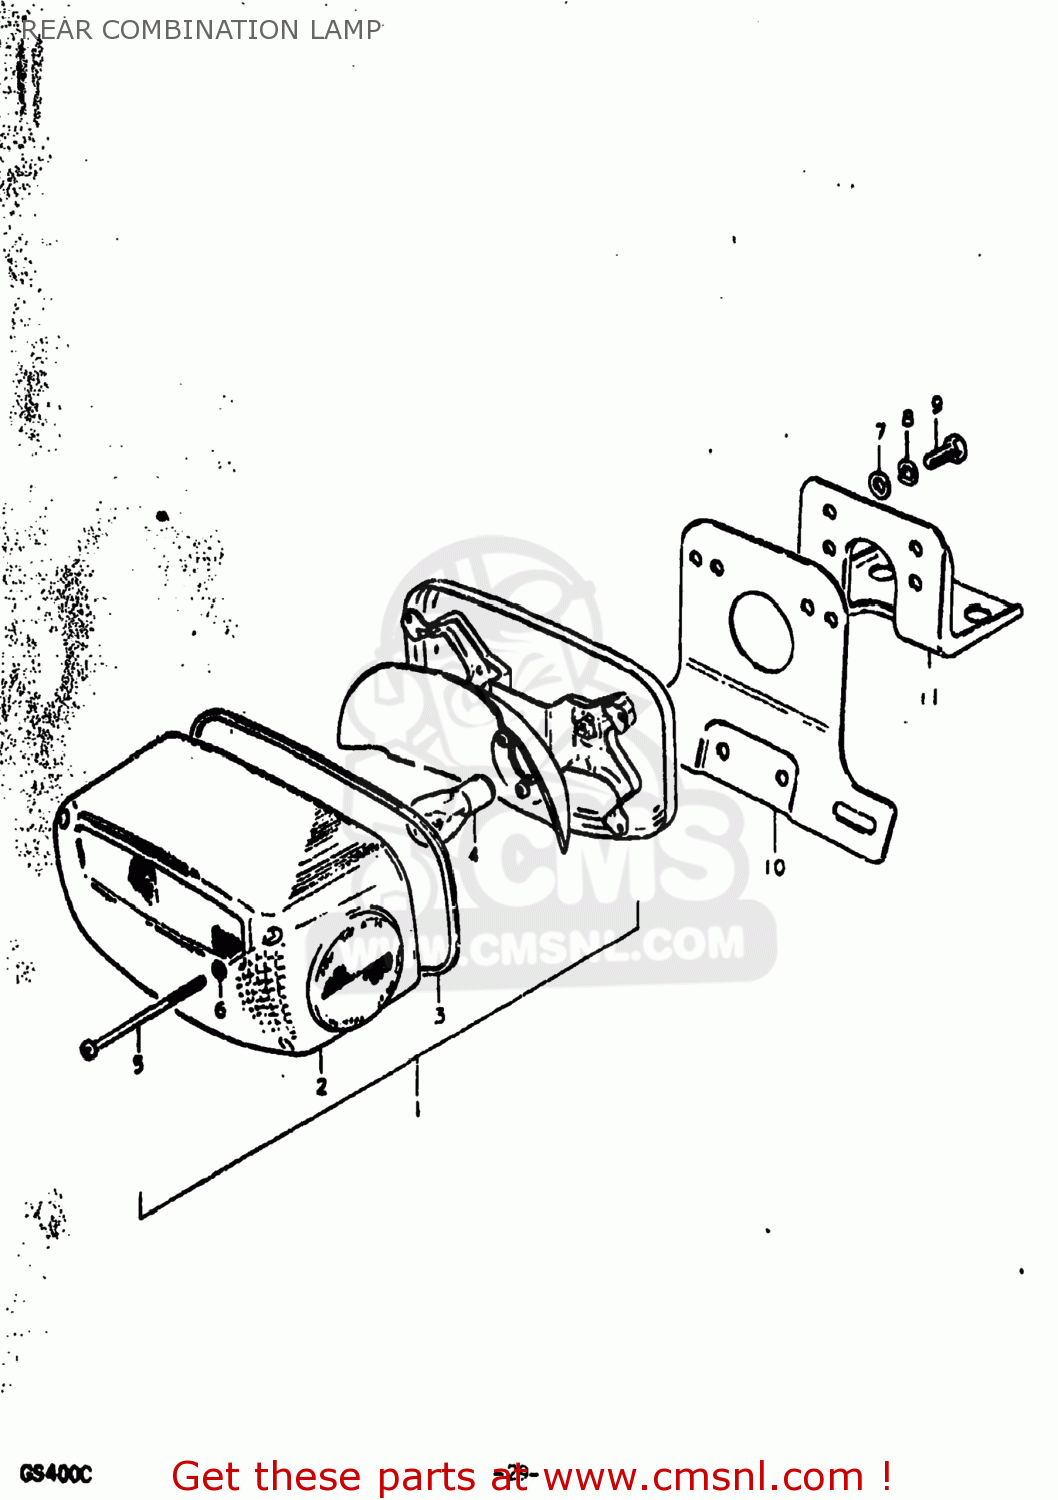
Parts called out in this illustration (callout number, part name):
1	LAMP ASSEMBLY,REAR COMBINATION
2	LENS,REAR COMBINATION LAMP
3	GASKET (NAS)
4	BULB(12V23W)
5	SCREW
6	GASKET (NAS)
7	WASHER
8	LOCK WASHER
9	BOLT
10	BRACKET,LICENSE PLATE
11	BRACKET,LICENSE PLATE
